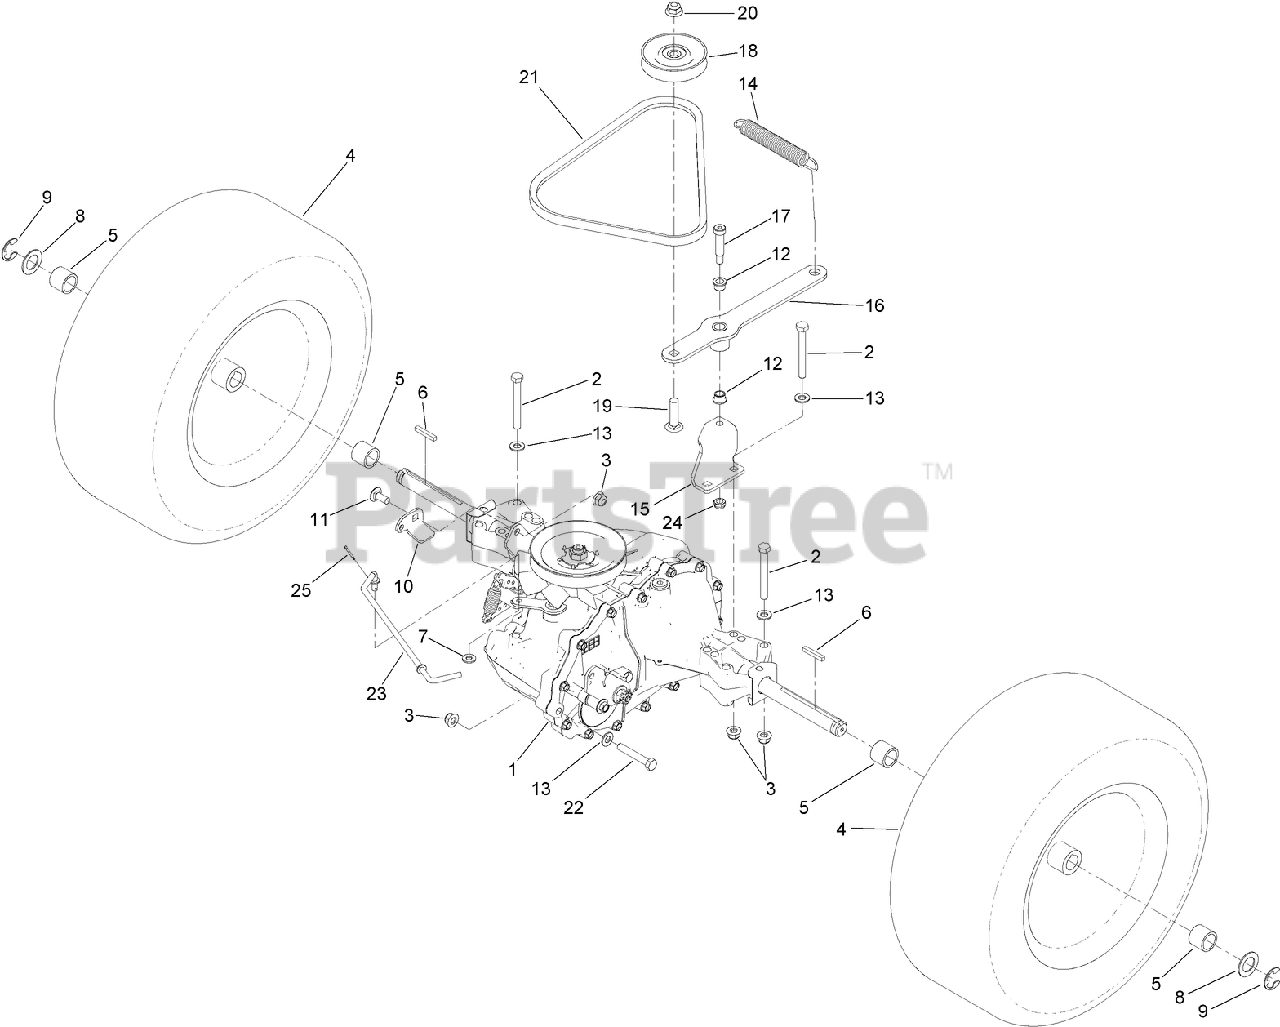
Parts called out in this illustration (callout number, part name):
1	TRANSAXLE ASM
2	SCREW-HH
3	NUT-HF, NI
4	TIRE ASM
5	SPACER
6	KEY-SQUARE
7	WASHER-FLAT
8	WASHER
9	E-RING
10	BRACKET-CABLE
11	SCREW-CARR
12	BUSHING
13	WASHER-PLAIN
14	SPRING-EXTENSION
15	MOUNT-ARM, TENSION
16	ARM-TENSION, BELT
17	SCREW-HSH
18	PULLEY
19	SCREW-CARR
20	NUT-HF, NI
21	V-BELT
22	SCREW-HH
23	LEVER-VALVE, TOW
24	NUT-LOCK, NI
25	PIN-COTTER
